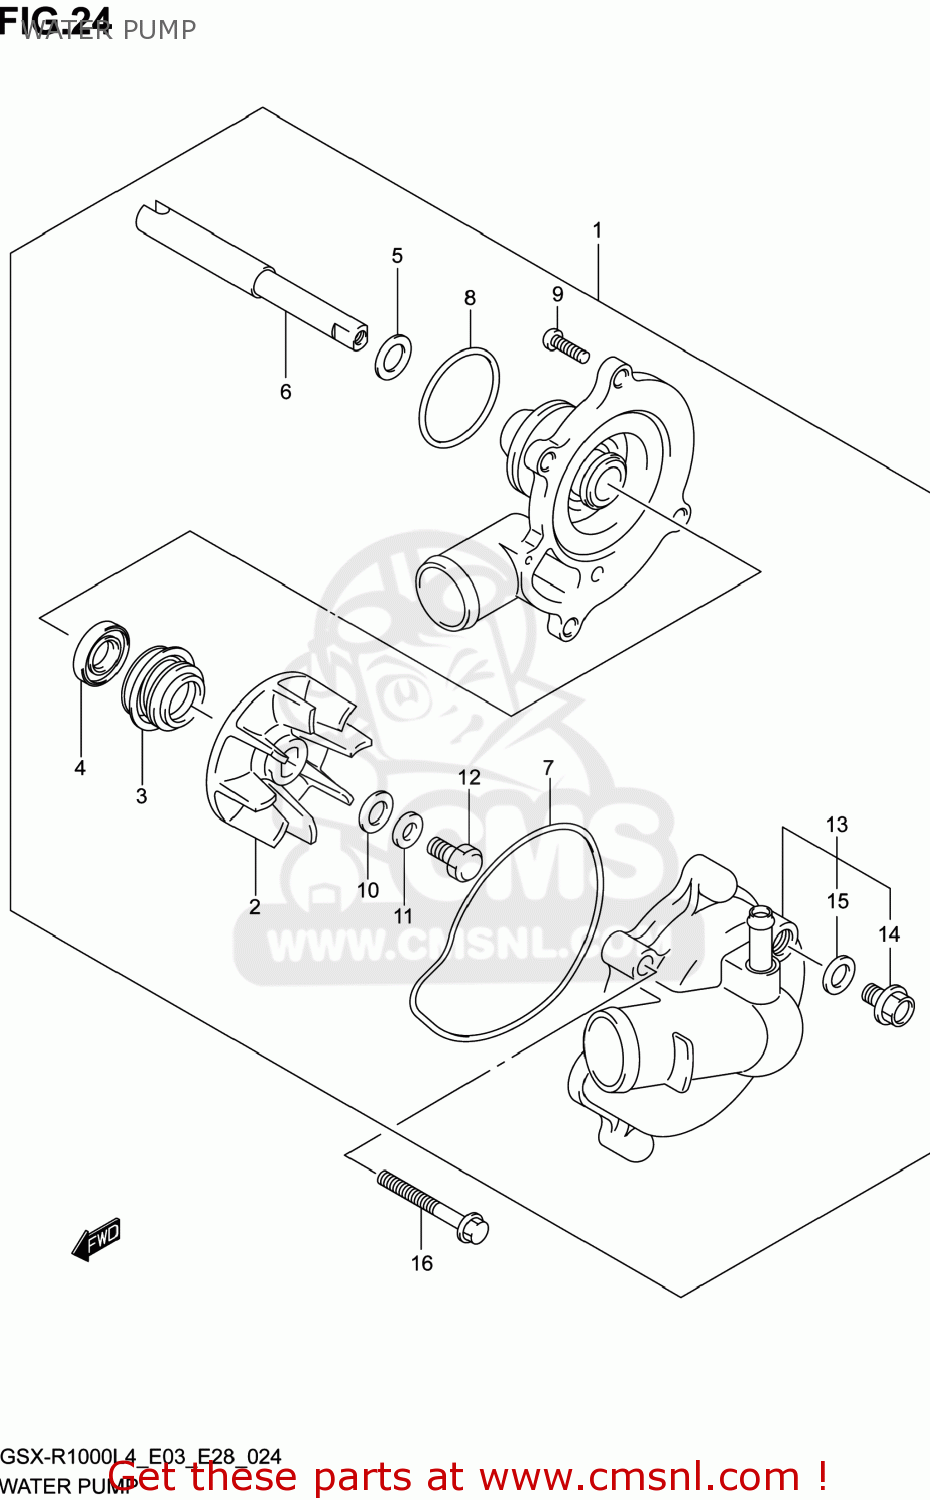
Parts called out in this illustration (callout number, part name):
1	PUMP ASSY,WATER
2	IMPELLER
3	SEAL,MECHANICAL
4	SEAL,OIL
5	WASHER
6	SHAFT
7	O RING
8	O RING,WATER PUMP HOLDER
9	SCREW
10	GASKET(6X15X2.2) (NAS)
11	WASHER
12	BOLT(6X13)
13	CASE,WATER PUMP
14	BOLT,DRAIN
15	GASKET(8.2X14X1) (NAS)
16	BOLT
